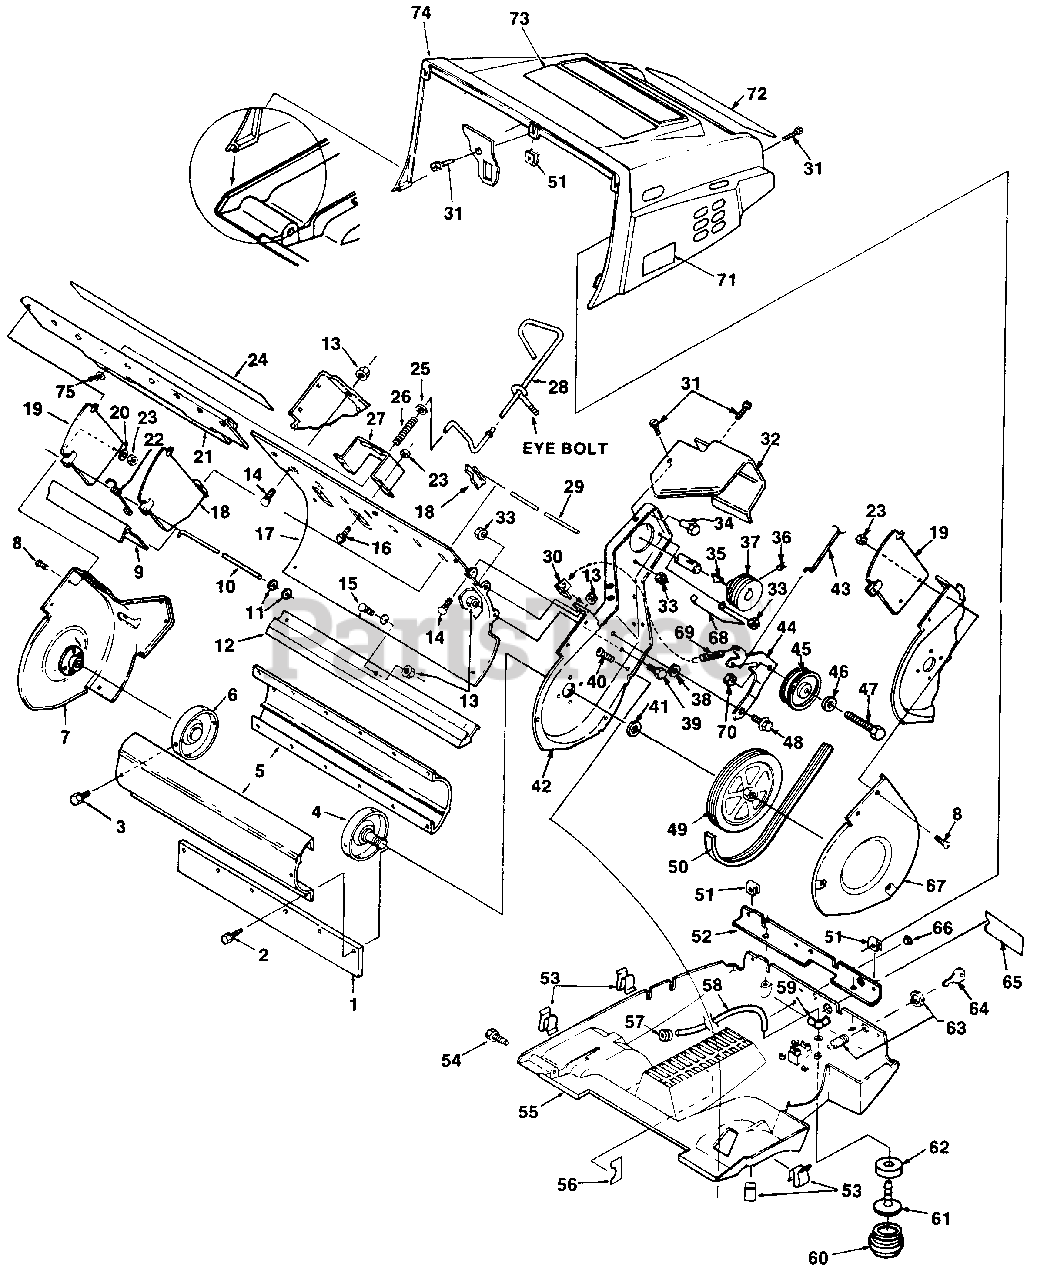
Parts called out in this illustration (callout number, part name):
1	PADDLE-impeller
2	SCREW-12-24 x 1"
3	BOLT- 1/4-14 x .44
4	DRIVESHAFT & PLATE KIT
5	DRUM-Impeller
6	END PLATE & PIN ASSEMBLY
7	FRAME- RH Side
8	SCREW- 10-24 x 5/8"
10	ROD- Retaining
12	BLADE-Scraper
13	NUT-Flange 1/4-20
14	BOLT- 1/4-20
15	BOLT- 1/4 x 3/4
16	SCREW- 10-24 x 5/8
17	HOUSING- Impeller
18	DEFLECTOR-Vane
20	WASHER-Retainer
21	PANEL Vane-Control
22	SPRING-R.H.
23	NUT-Stop 10-24
24	DECAL-Warning
25	WASHER 5/16
27	BRACKET- Control rod
28	ROD-Chute control
30	CLIP-Spring
31	SCREW- 10-24 x 3/4"
32	SHIELD- Belt
33	NUT-Flange 5/16-18
34	NUT- 5/16-18
35	KEY- 5/8 x 5/32
36	SCREW-Set 1/4-20 x 3/8"
37	PULLEY-Drive
39	SCREW- 1/4-20 x 1/2
40	SCREW- 1/4-10 x 5/8
42	FRAME-Side (L.H.)
43	CABLE & SPRING
44	ARM-Idler
46	WASHER 3/8
47	SCREW- 3/8-16 x 1 1/2
49	PULLEY-Driven
50	BELT-Drive
51	NUT-Speed #10
52	BRACKET-Control panel
53	SCREW- Thd. #10 x 5/8
54	SCREW- 1/4-20 x 5/8
55	COWLING- Lower
56	DECAL-Fuel valve
58	TUBE-RUBBER 17"
59	WING NUT- 1/4-20
60	BULB-Fuel primer
61	FITTING- Fuel primer
62	CUP- Fuel primer
63	SWITCH-Ignition
64	KEY- Ignition
65	DECAL-Electric start
67	GUARD- Belt
68	GUIDE-Belt
69	SPRING-EXTENSION
70	NUT- Hex lock 3/8-16
71	DECAL- Warning
72	DECAL-Console
73	COWLING-Upper
75	NUT- Speed #10
